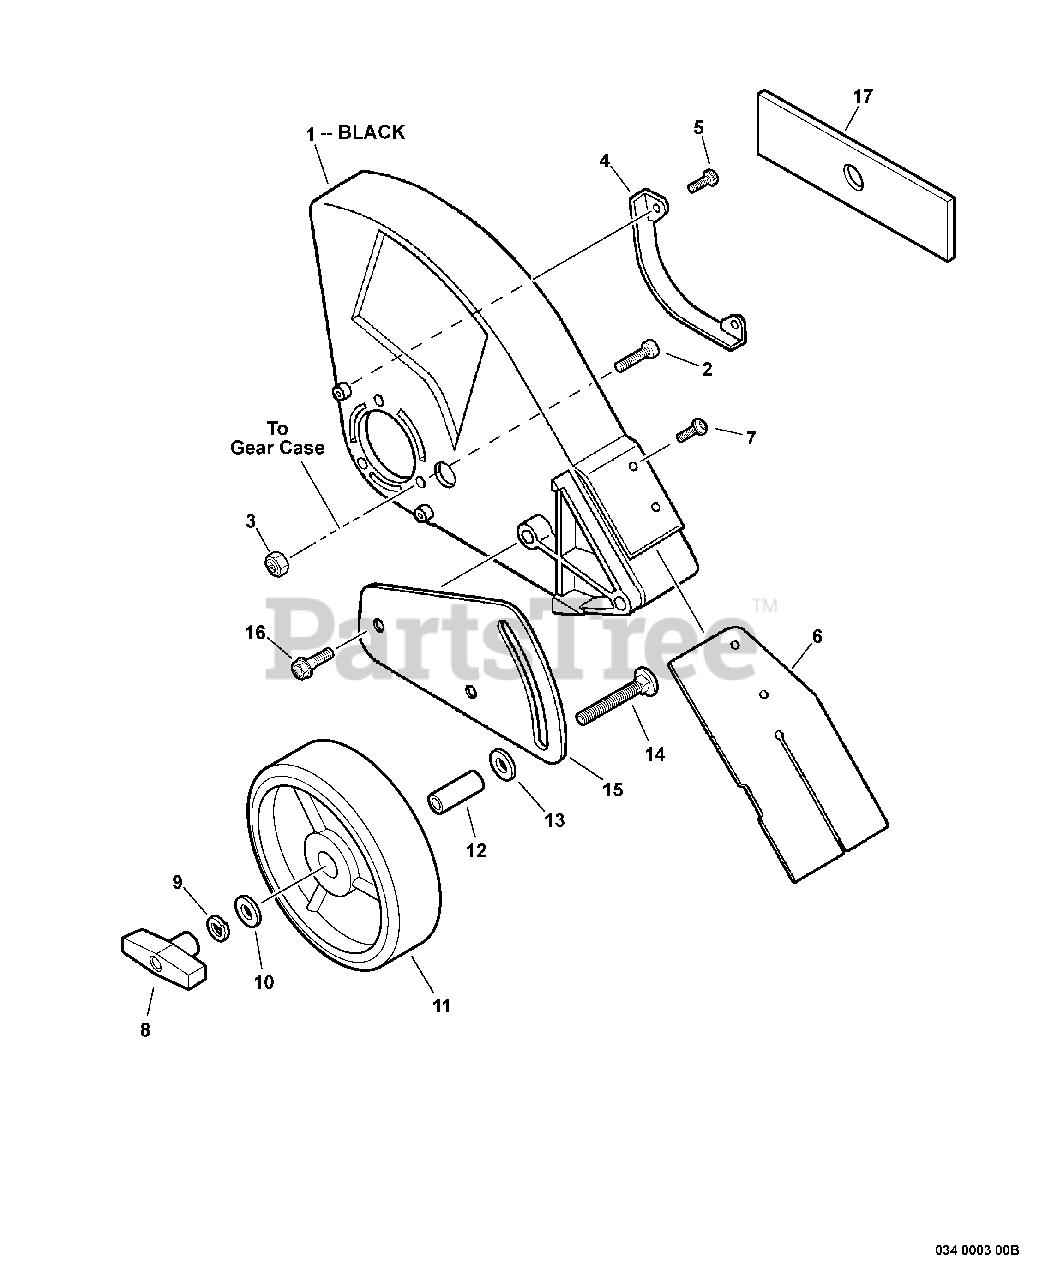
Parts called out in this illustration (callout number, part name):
1	SHIELD, DEBRIS
2	SCREW - 5X20
3	LOCKNUT - 5
5	SCREW - 4X16 -- TAPPING
6	FLAP, DEBRIS
7	SCREW - 4X20 -- TAPPING
8	WINGNUT - 5/16-18
9	LOCKWASHER - 8
10	WASHER - 8
11	WHEEL - 6X1.5
12	COLLAR - 12
13	WASHER - 10
14	BOLT - CARRIAGE
15	BRACKET, WHEEL
16	BOLT - 8
17	BLADE, EDGER
